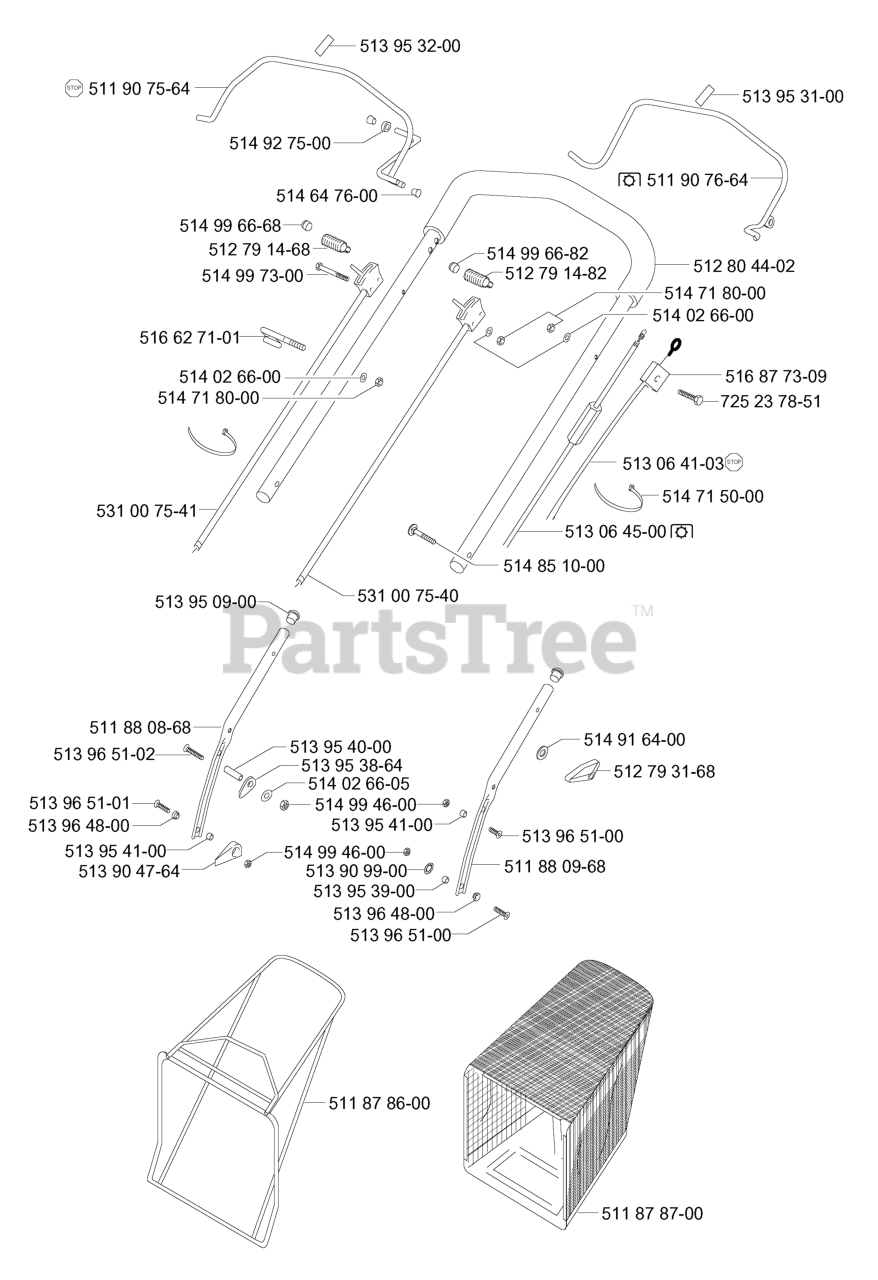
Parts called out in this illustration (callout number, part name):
1	HOUSING 42 CLEARCUT TRACTOR WE
2	MANDREL ASM, CAST IRON
6	BLADE 42 CLEARCUT EURO NON-REV
8	NOSE ROLLER 48"
9	ROD.ROLLER.NOSE.NARROW.48"
10	PIN.COTTER.5/16.BOW TI
13	ROD.HINGE
14	STUD.FASTNER.W/ANTI-ROTATE
17	NUT LOCK HEX FLANGE 5/16-18
24	5/16-18 NYLOC FLANGE NUT
27	PULLEY.IDLER.MWR.STATI.LH
28	ARM.42"FCS.CLUTCHING.X431
29	CARRIAGE BOLT 3/8-16 X
30	PULLEY.IDLER.2006
39	SHIELD.42.CLEARCUT.RH.DECK.431
40	WHEEL.GAUGE.RALLY
41	BOLT.SHOULDER.3/8-16X3-5/8.
42	ARM.SUSPENSION.MOWER
43	NUT LOCK FLG 3/8-16 UNC
44	BOLT.SHOULDER
46	BELT.42.CLEARCUT.DECKDRIVE.EUR
47	BOLT 5/16C X 3/4" CARRIAGE
48	SPRING.42.FCS.DEFLECTOR
49	SHIELD.42CLRCUT.LH.DECK.SD.431
51	PULLEY.MANDREL.5.438.PD
52	SCREW.7/16-14 X 2.125.WASHER
53	PORT.WASHOUT
55	EYE BOLT 5/16 X 3.50
56	SPRING.EXTN.42.FCS.TR.DECK.DRV
57	NUT 5/16C WHIZ
61	BOLT.HEX.WASHR.HED.313-18X1.19
64	BOLT.WASHER.ASM.7/16-2
65	NUT PUSH M
66	DEFLECTOR.ASM.42.FCS.ORANGE
67	SCREW.1/4-20X5/8
68	KEEPER.BELT.IDLER.54"T
69	COVER.42.CLRCUT.EU.MANDREL.498
72	CAP-SLEEVE LT
73	PALNUT 1/4
74	SHOULDER BOLT 5/16-18TT
75	BUMPER.42CC.TRIM.SIDE.ASSY.HUS
77	WASHER.5/16.FLAT.STE.STD.
78	BRACKET.PNT.GA-WHEEL.FCS.42.RH
79	BRACKET.PNT.GA-WHEEL.42FCS.LH
81	BUSHING.NOSE.ROLLER
83	SCR 1/4-20X5/8 HEX SELF TAP ZD
